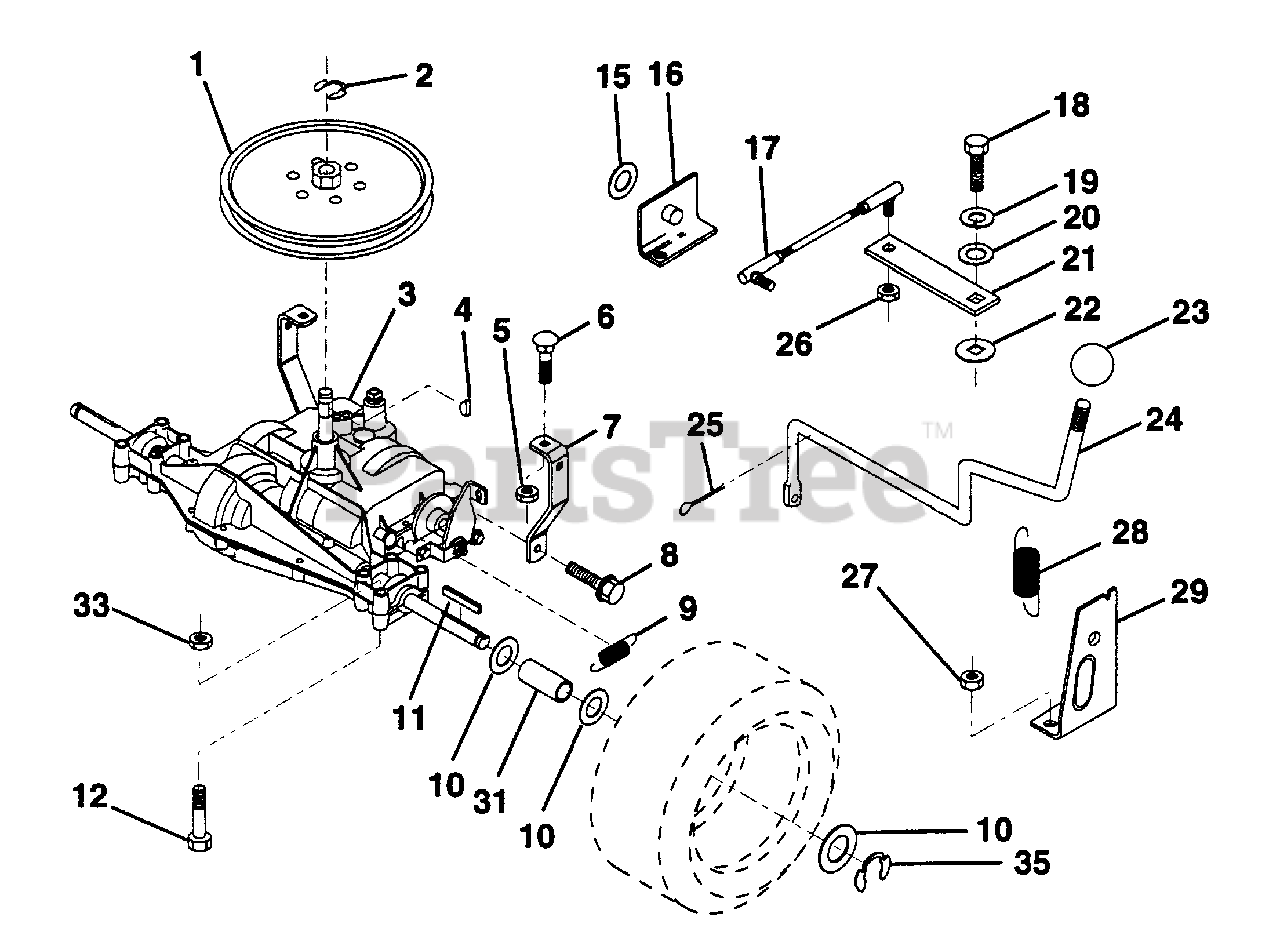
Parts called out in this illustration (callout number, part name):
2	Ring, Retainer
3	Transaxle Dana
4	Key, Woodruff #9
5	Nut, Crownlock 5/16-18
6	Bolt, Carriage 5/16-18 UNC x 3/4
7	Strap, Torque
8	Screw 5/16-18 x 3/4
9	Spring, Brake
10	Washer 25/32 x 1-1/4 x 16 Gauge
11	Key, Square
12	Bolt, Hex, Fin. 3/8-16 Unc x 2-3/4
15	Washer 17/32 x 1 x 16 Gauge
16	Support Handle Shift, LH
17	Link, Shift
18	Bolt, Hex, Fin. 1/4-28 UNF x 3/4 Grade 8
19	Washer, Lock 1/4
20	Washer 9/32 x 3/4 x 10 Gauge
21	Arm, Shift
22	Washer, Shift Plate
23	Knob, Duckhead
24	Rod Assembly, Shift
25	Pin, Cotter 1/8 x 1
26	Locknut 5/16-24 UNF
27	Nut, Hex, Keps 5/16-18
28	Extension, Spring
29	Support Handle Shift, RH
31	Spacer Split
33	Nut Crownlock 3/8-16 Unc
34	Washer, External Tooth 5/16
